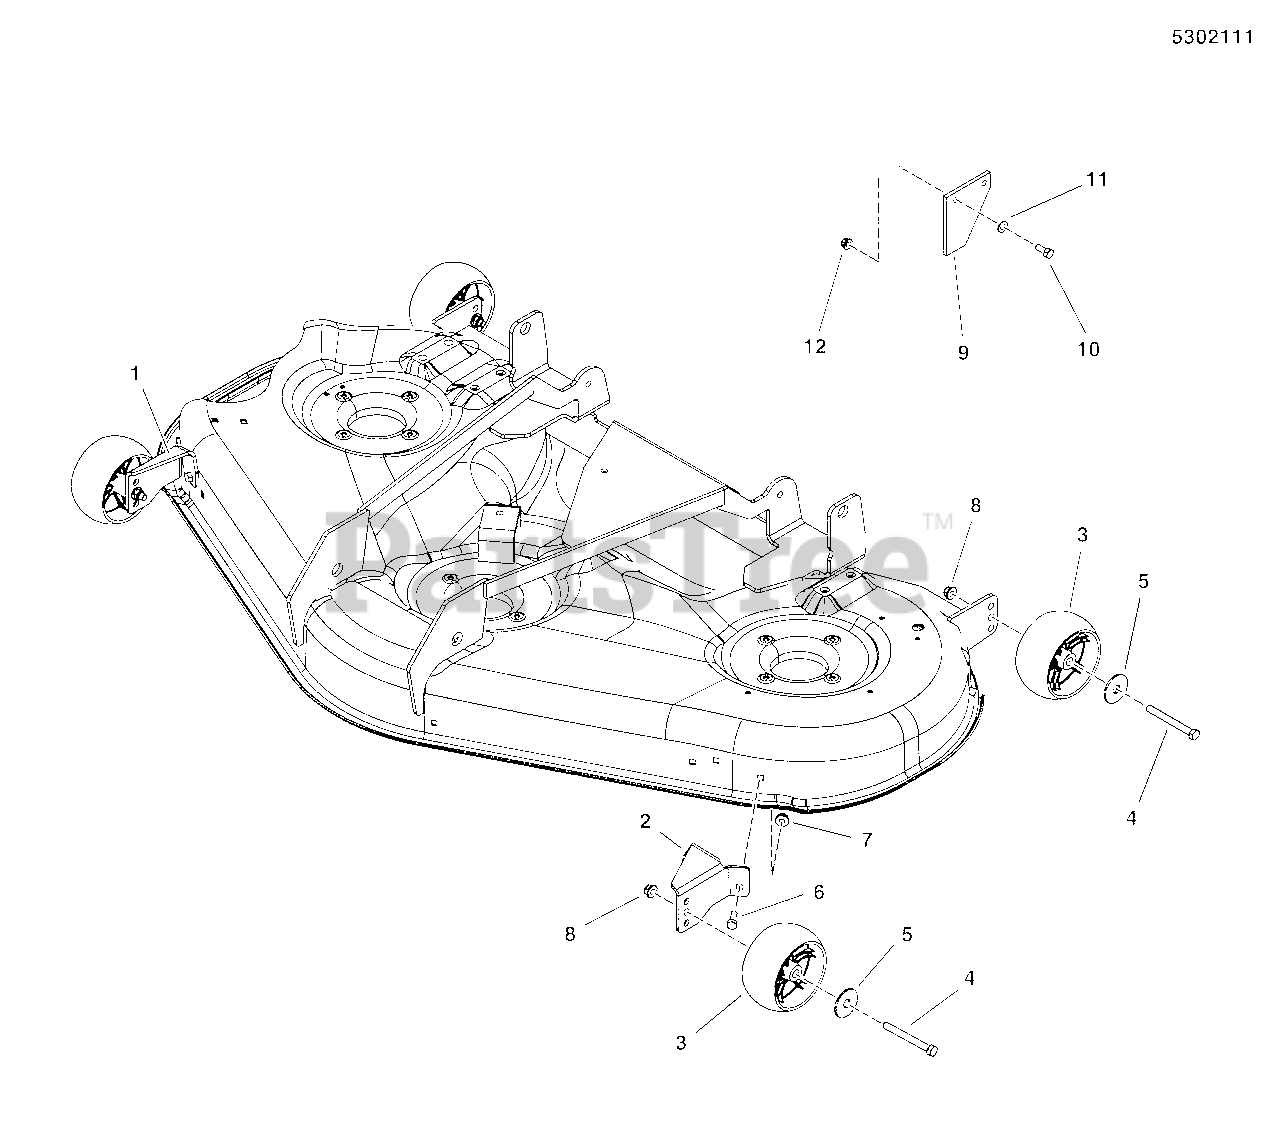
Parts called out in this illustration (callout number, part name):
1	BRKT, GAUGE WHEEL, RH
2	BRKT, GAUGE WHEEL, LH
3	WHEEL, GAUGE BLACK POLY 5" DIA
4	BOLT, SHLDR 3/8-16X3.41 .750 THRD YELLOW
5	WASHER, 0.500(0.51IDX1.00ODX.10THK) BLK
6	BOLT, RD HD SH SQ NK 5/16-18X0.875 G5 BLK
7	NUT, HEX FLANGE 3/8-16 ESNA BLK
8	NUT, 3/8-16 HEX NYLOCK FLANGE
9	PLATE, DECK STOP
10	BOLT, 5/16-18 X 3/4 GD5
11	WASHER, 5/16" SAE
12	NUT, 5/16-18 HEX NYLOCK FLANGE
